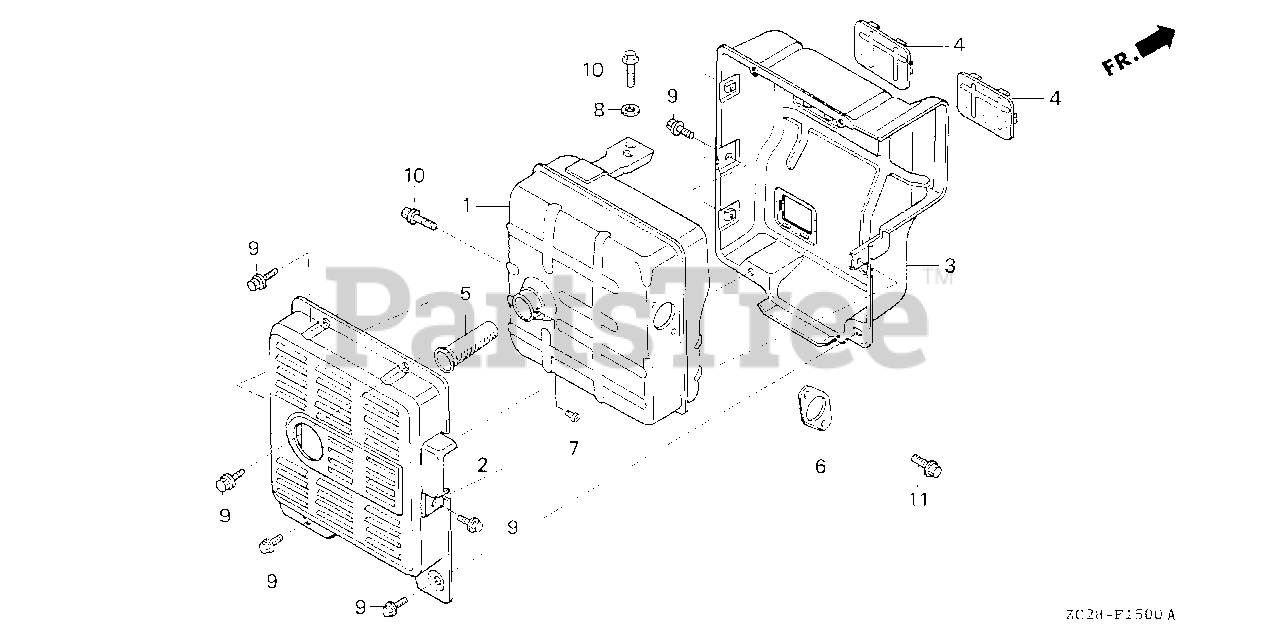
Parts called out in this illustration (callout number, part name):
1	MUFFLER
2	PROTECTOR, MUFFLER (OUTER)
3	PROTECTOR, MUFFLER (INNER)
4	SEAL, MUFFLER PROTECTOR
5	ARRESTER, SPARK
6	GASKET, EX. PIPE
7	SCREW, TAPPING (4X6)
7	SCREW, TAPPING (4X8)
8	WASHER, PLAIN (8MM)
9	BOLT, FLANGE (6X10)
10	BOLT, FLANGE (8X16)
11	BOLT, FLANGE (8X20)
